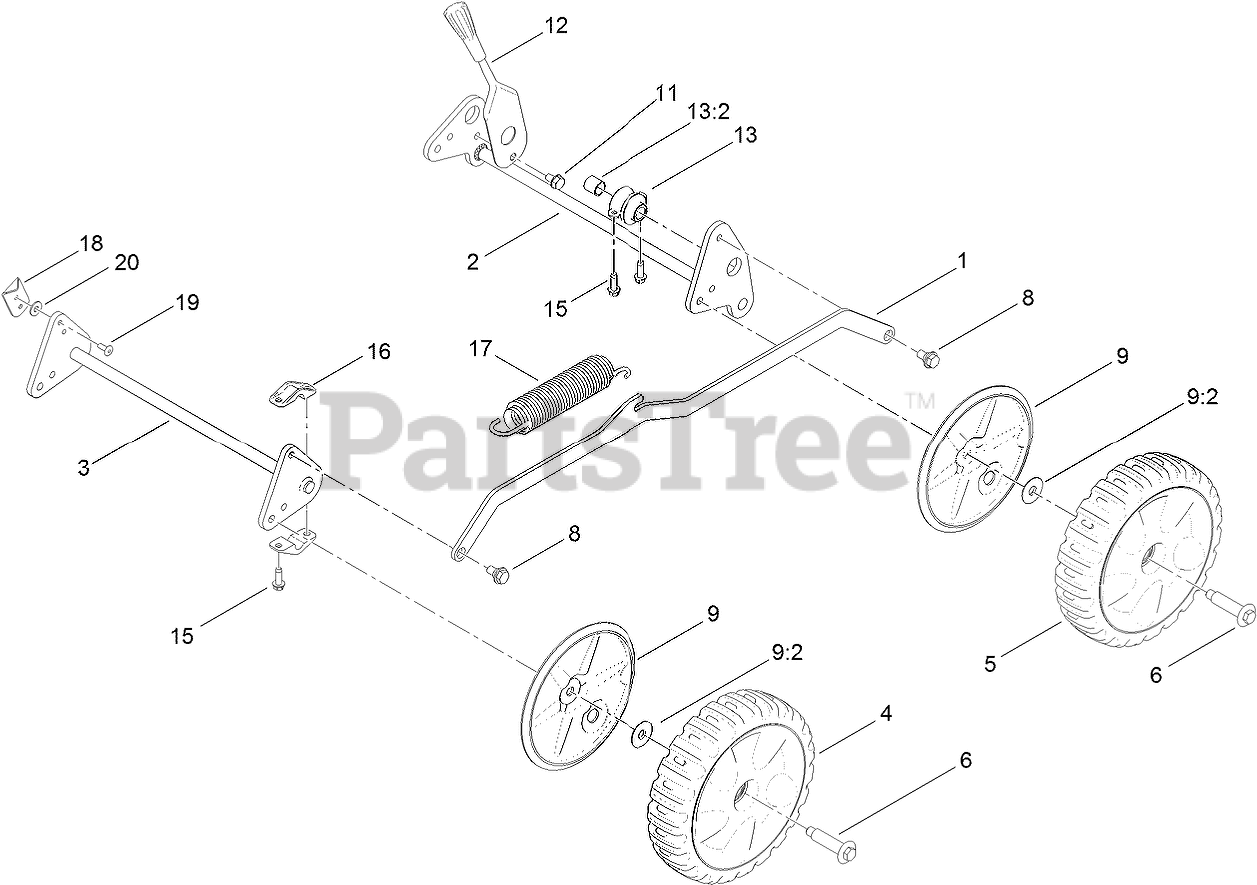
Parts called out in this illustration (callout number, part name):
1	BAR-CROSS, HOC
2	BAR-PIVOT, REAR
3	BAR-PIVOT, FRONT
4	8 INCH WHEEL ASM
5	8 INCH WHEEL AND GEAR ASM
6	BOLT-SHOULDER
8	SCREW-SHOULDER
9	WHEEL COVER ASM
9:2	WASHER-STEPPED
11	SCREW-HHF
12	HANDLE-LIFT ASSIST
13	BUSHING ASM
13:2	BUSHING
15	SCREW-HWHTF
16	MOUNT-AXLE, FRONT
17	SPRING-EXTENSION
18	INDICATOR-HOC
19	RIVET-BLIND
20	WASHER-FLAT
